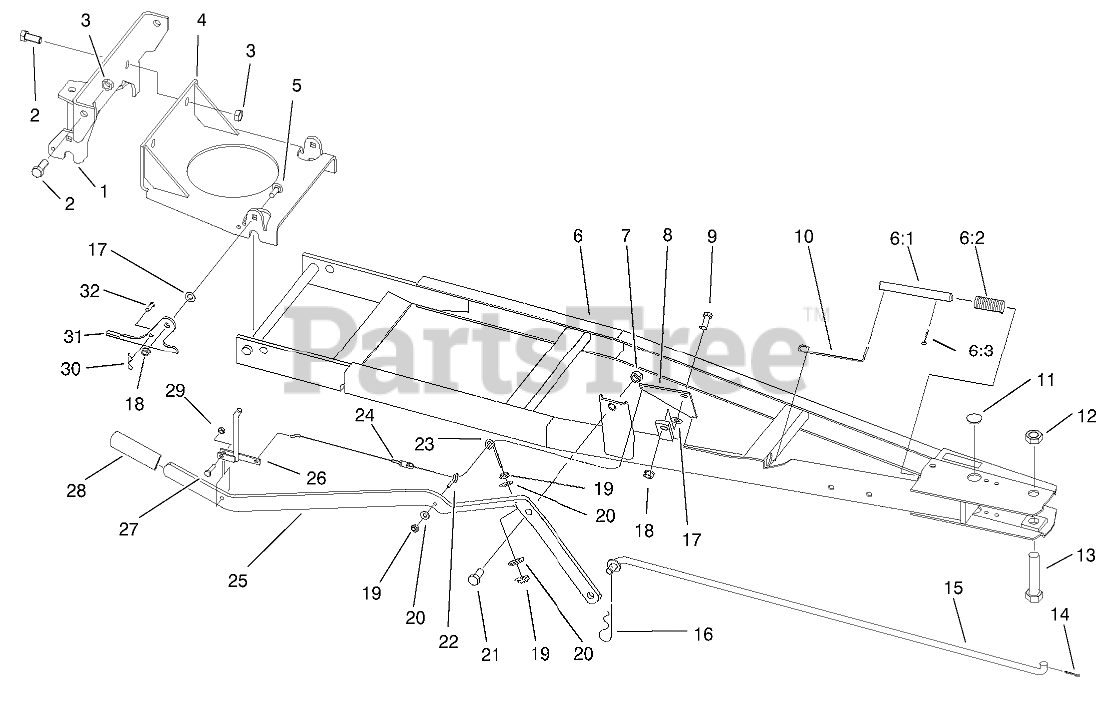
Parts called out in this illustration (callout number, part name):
1	BRACKET-MOUNTING
2	SCREW-HH
3	NUT-LOCK, NI
4	BRACKET-BLADE MOUNT
5	BOLT-CARR
6	FRAME-BLADE
6:1	PIN-INDEX
6:2	SPRING-COMPRESSION
6:3	PIN-COTTER
7	NUT-JAM
8	PLATE - INDEX
9	SCREW-HH
10	ROD-LOWER INDEX
11	PLUG
12	NUT-LOCK
13	SCREW-HH
14	PIN-COTTER
16	PIN-HAIR
17	WASHER-FLAT
18	NUT-LOCK, NI
19	NUT-LOCK, NI
20	WASHER-FLAT
21	SCREW-HH
22	EYEBOLT
23	EYELET - CABLE
24	CABLE ASM - LIFT
25	LEVER - INDEX BLADE
26	LEVER-INDEX
27	SCREW-HH
28	GRIP
29	NUT-LOCK
30	PIN-HAIR
31	PLATE-LATCHING
32	PIN-CLEVIS
